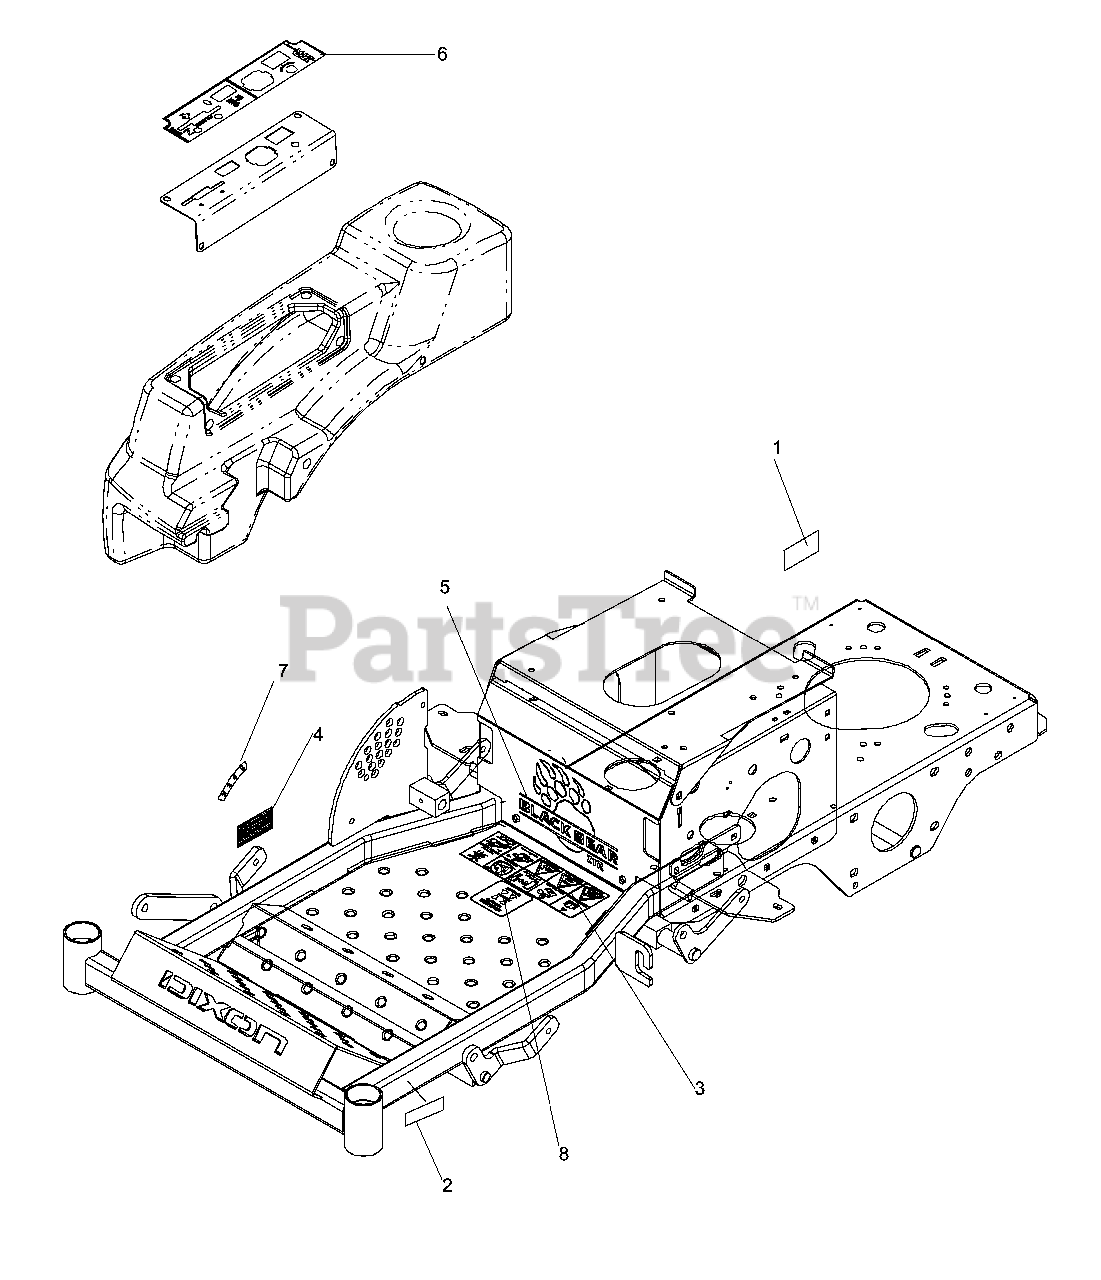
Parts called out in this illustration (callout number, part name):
1	DECAL, PARKER
2	DECAL, KAWASAKI
3	DECAL, SAFETY WARNING
4	DECAL, FLAG
5	DECAL BLACK BEAR
6	DECAL CONTROL PANEL
8	DECAL, DRIVE LEVERS
